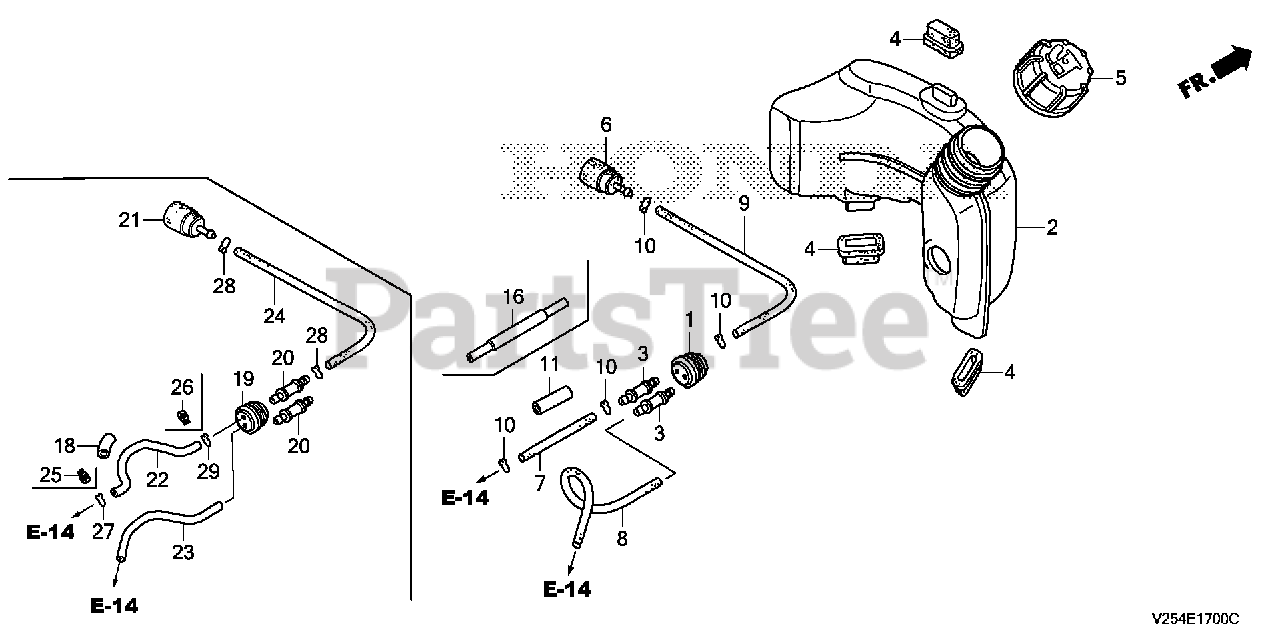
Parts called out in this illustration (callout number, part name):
2	TANK, FUEL
4	RUBBER, TANK MOUNTING
5	CAP ASSY., FUEL TANK
18	PROTECTOR, TUBE
19	GROMMET, FUEL TUBE
20	JOINT, FUEL TANK
21	FILTER, FUEL
22	TUBE, FUEL
23	TUBE, FUEL RETURN
24	TUBE A, FUEL
25	CLAMP, TUBE (D5.5)
26	CLAMP, TUBE (D5.5)
28	CLIP, TUBE (B1 5)
